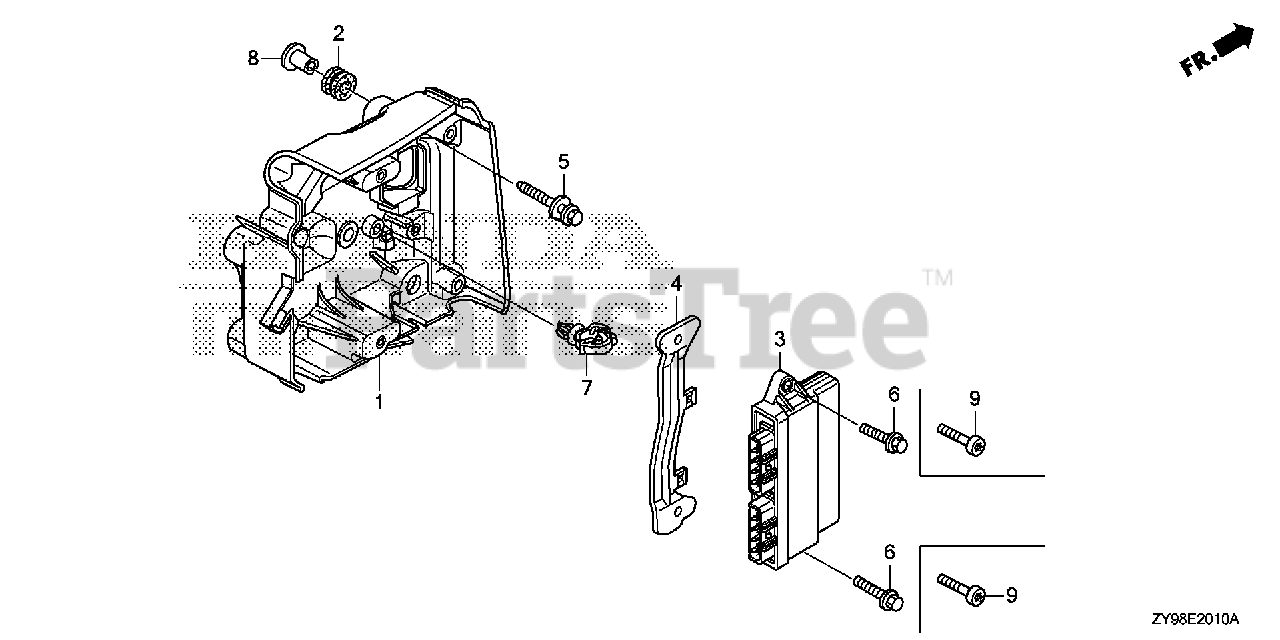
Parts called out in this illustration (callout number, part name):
1	CASE, ELECTRONIC PARTS
2	GROMMET, ELECTRONIC PARTS CASE
3	CONTROL UNIT, ELECTRONIC
4	BRACKET, ELECTRONIC CONTROL UNIT
5	BOLT-WASHER (6X27) (CT200)
6	BOLT, FLANGE (6X20)
7	CLIP, WIRE HARNESS
8	COLLAR, MODULE IGNITION CONTROL CASE (CDI)
9	BOLT, TORX (M6X20)
